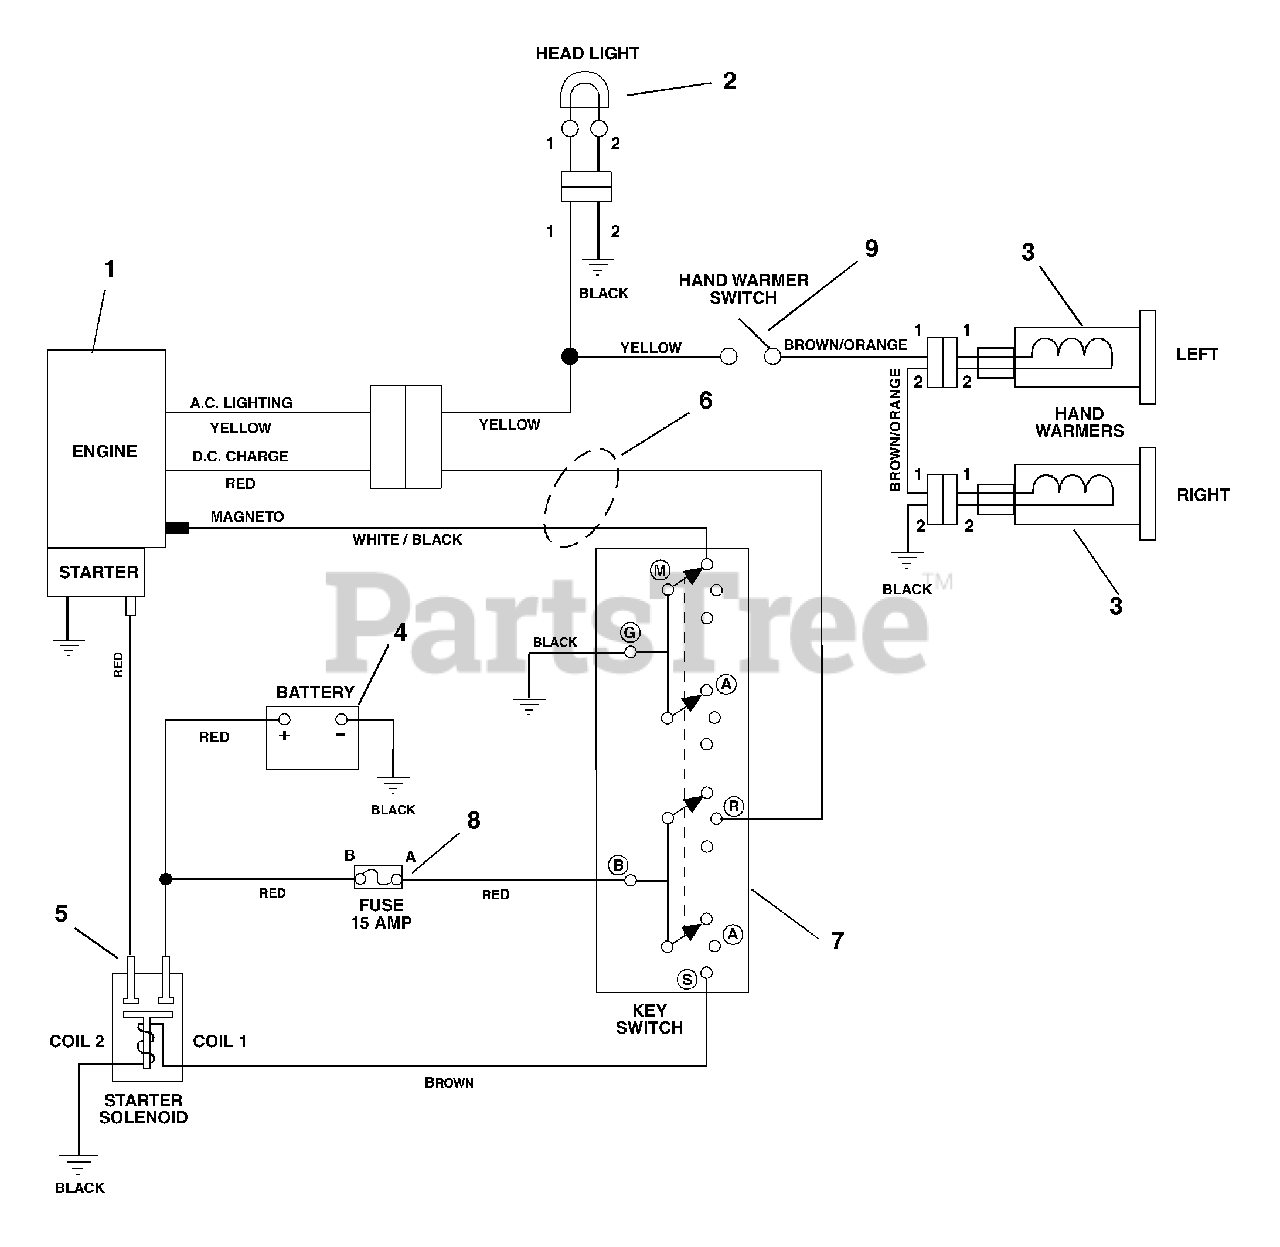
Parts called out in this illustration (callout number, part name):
1	ENGINE, 10HP OHV TEC.-12 VOLT
2	HEADLIGHT
3	WARMER, HAND W/TERMINAL
4	Battery
5	SOLENOID
6	WIRE HARNESS 12V, HG&L
7	SWITCH ASSEMBLY
8	FUSE, 15 AMP.
9	SWITCH, ON/OFF
